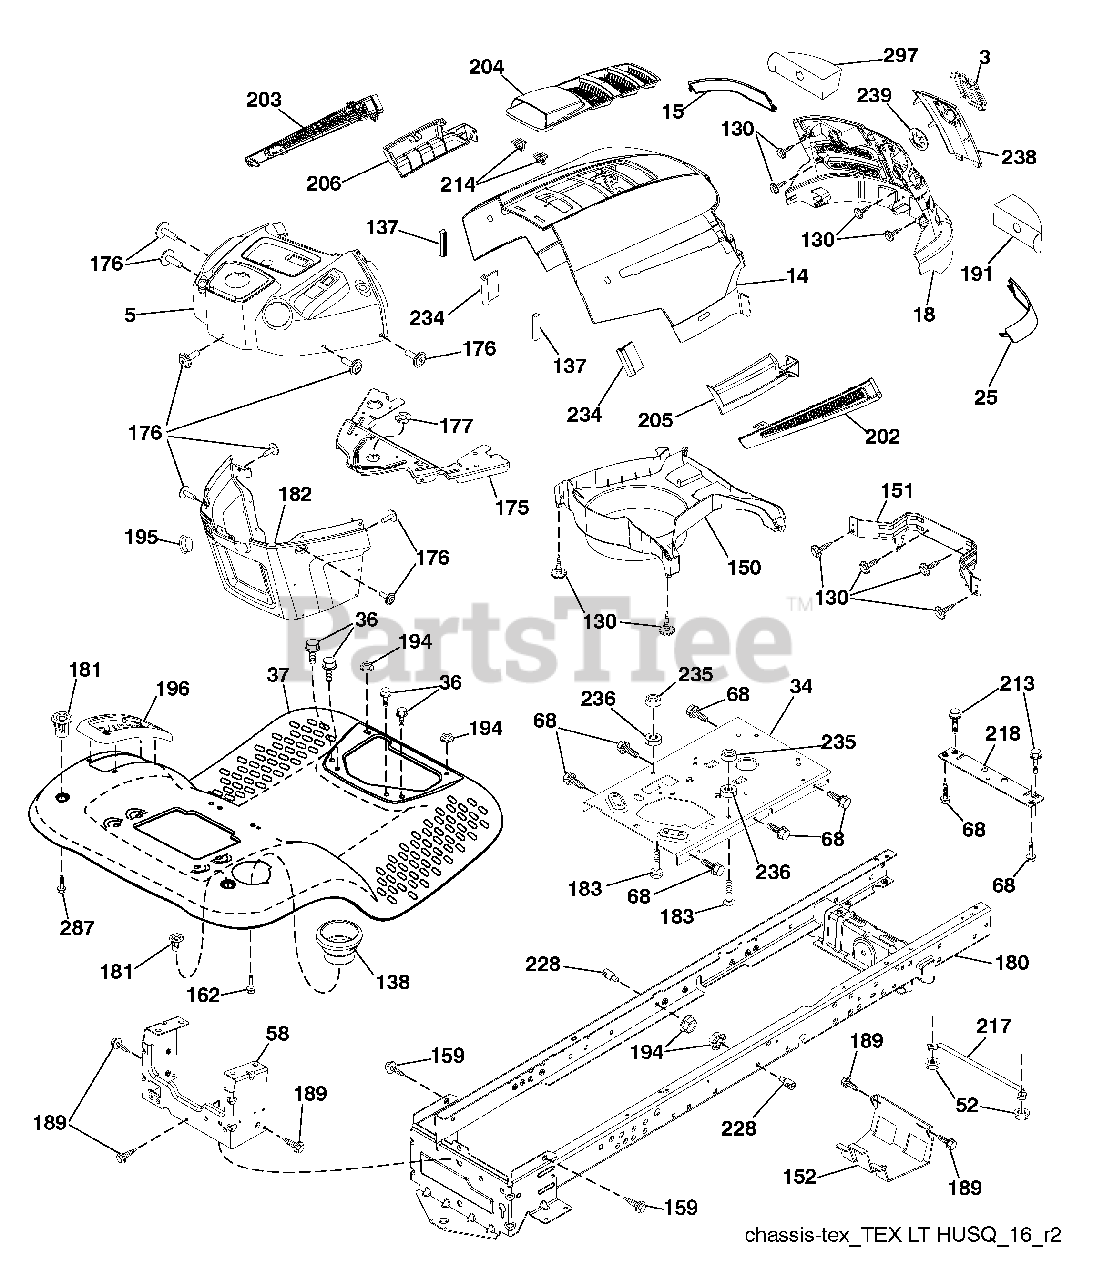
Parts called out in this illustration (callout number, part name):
3	Logo
5	Dash
14	Hood
15	Lens LH
18	Grille
25	Lens RH
34	Plate Engine
36	Screw 5/16-18 x 3/4
37	Fender
52	Nut Crown Lock 5/16
58	Drawbar Upper
68	Screw THDROL 5/16-18 x 1/2
130	Screw #10 x 0.750 BOS Thread
137	Bumper Dash
138	Cupholder
151	Bracket Pivot
152	Shield Browning
159	Screw Hexwash Thor 3/8-16 x 3/4
175	Crossmember Plate
176	Screw 10-24 x 5/8
177	Bushing Steering
181	Bushing Mtg. Fender Crgo
182	Dash Lower
183	Bolt 5/16-18 x 1-1/4 Full Thd
189	Screw 5/16-18 x 3/4
191	Insert Reflective RH
194	Nut Lock Hex Flange 5/16-18
195	Plug Dash
196	Console Asm. Deck Lift
202	Vent Side Hood RH
203	Vent Side Hood LH
204	Vent Top Hood
205	Skirt Side RH
206	Skirt Side LH
213	Bolt 5/16-18 x 3/4
214	Clip Retainer
217	Rod Pivot Hood
218	X-Piece Hood Stop
228	Stud Fastener
234	Bumper Hood
235	Spacer Fender
236	Nut Lock 5/16-18 unc
238	Trim
239	Clip Tinnerman
287	Screw Hex Washead 1/4-20 x 3/8
297	Insert reflective LH
